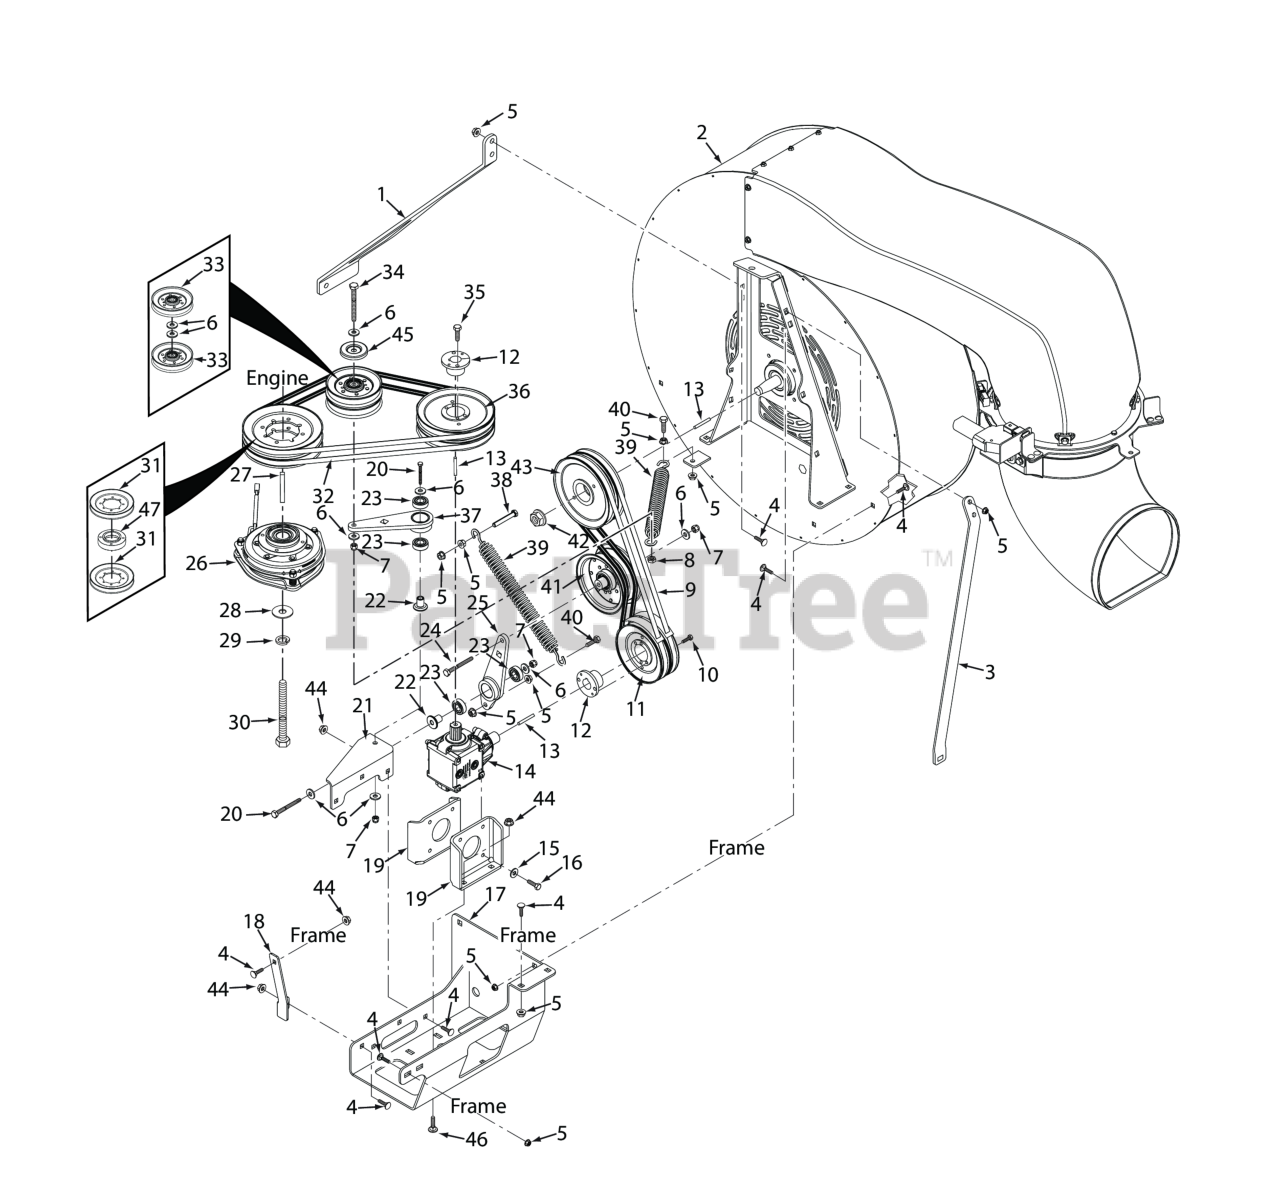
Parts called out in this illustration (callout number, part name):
1	LH Support Bar, Blower
2	Blower Housing, With Decal
3	RH Support Bar, Blower
4	Carriage Bolt, 3/8-16 x 1.0"
5	NUT, 3/8-16 SERRATED FLANGE HEX HEAD
6	Flatwasher, 3/8 (.391 x .938 x .105 HD) Grade 8
7	HEX NUT, ELASTIC STOP LOCK, 3/8-16
8	Bolt, Hex Head 3/8-16 x 1" Ser. Flg.
9	C-Belt, Gearbox Output
10	Hub, Tapered, 1" Bore
11	Pulley, Double Groove
12	TAPERED HUB, 1.00" BORE
13	Key, 1/4 x 1/4 x 1.25" Pulley Mtg.
14	Gearbox Assembly
15	Lockwasher, 5/16 (.317 x .586 x .078) Helical Spring
16	Bolt, Heax Head 5/16-18 x 1" (48V / 52V)
17	Mounting Bracket, Gearbox
18	Support Strap, Gearbox
19	Mounting Plate, Gearbox
20	Bolt, Hex Head 3/8-16 x 2-1/4" - 61"
21	Idler Arm Bracket, Gearbox
22	Pivot, Idler Short
23	BEARINGS, BALL, NEUTRAL RETURN
24	Bolt, Hex Head 3/8-16 x 3" - 52"
25	Idler Arm Assembly, Gearbox Output (INCL. 23)
26	Clutch, GT3.5 (28.6mm Bore)
27	Key, 1/4 x 1/4 x 3-1/2"
28	Flatwasher, 7/16-.469 x 1.75 x .25 (48, 52)
29	Lockwasher, 7/16� Spring
30	Bolt, Hex Head 7/16-20 x 3" w/t Patch
31	Pulley, Clutch 7.30 DIA
32	Belt, Gearbox Input
33	IDLER PULLEY, "V" GROOVE
34	Capscrew, Hex Head 3/8-16 x 3-3/4"
35	Bolt, Hex Head 1/4-20 x 1" Grade 8 Black
36	Pulley, Gearbox Input, 6.95 DIA, Double Groove
37	Idler Arm Assembly, Gearbox Input (INCL. 23)
38	Bolt, Hex Head 3/8-16 x 2-1/2" Grade 8
39	Spring, Transmission Drive
40	Bolt, Hex Head 3/8-16 x 1-1/2" Grade 8 Black
41	Pulley, Idler 5" Dia.
42	Nut, 3/4-16 Spriral Lock
43	Pulley, Blower, 6.95 DIA, Double Groove
44	Nut, Flange Elastic Stop Nut, 3/8-16
45	Quick Pin, 5/16" Dia.
46	Bolt, Carriage 3/8-16 x 1"
47	Hub, Clutch Pulley
